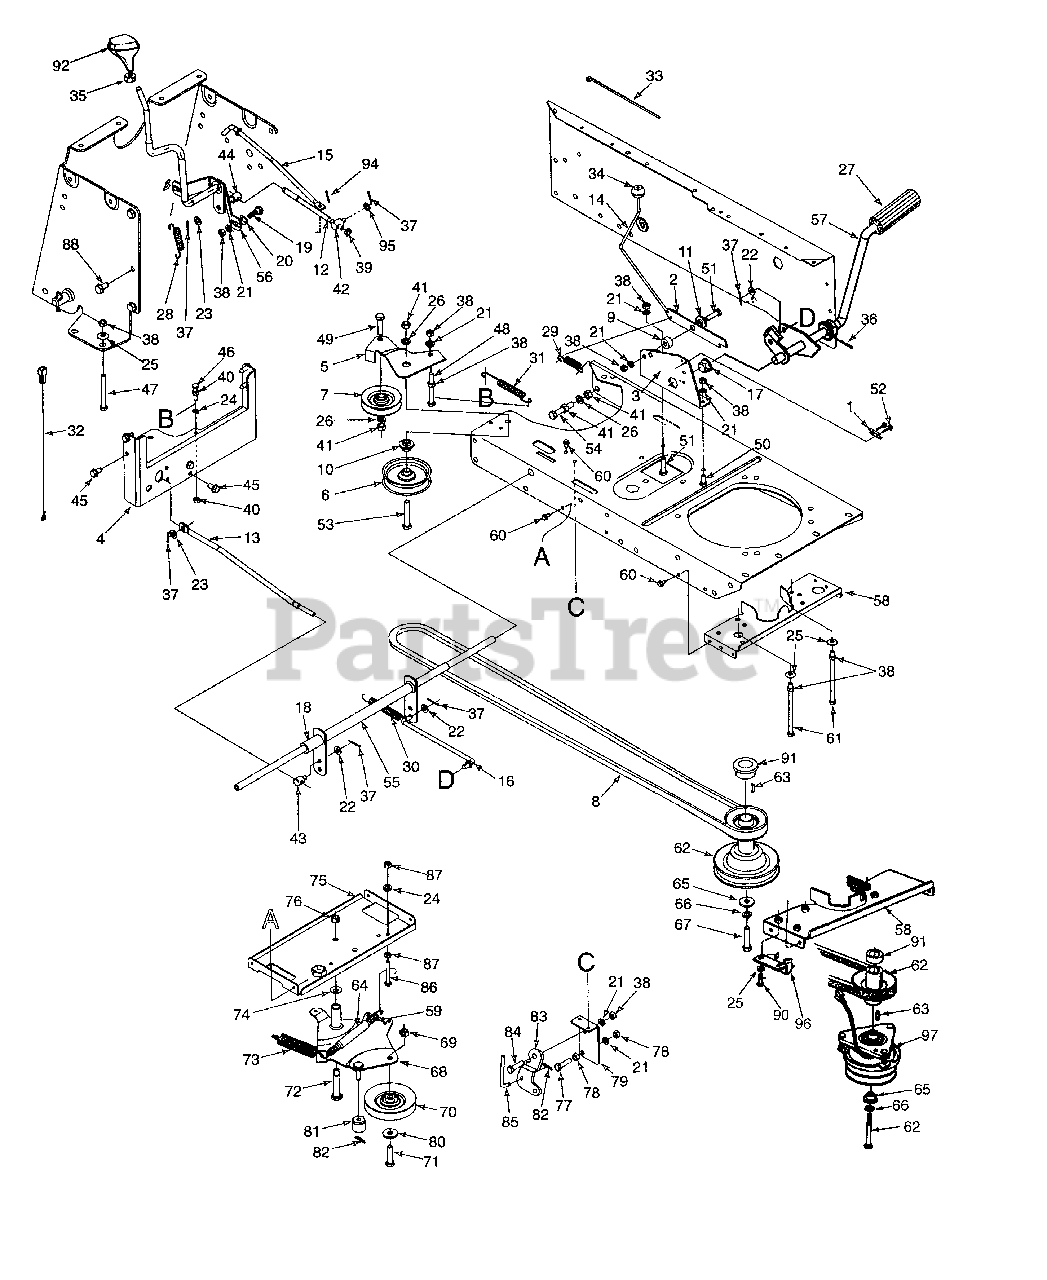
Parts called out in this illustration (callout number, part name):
1	Switch Plate
7	Idler Pulley
8	"V"-Belt
9	Spacer .34" I.D. x .44" Lg.
10	Shld. Spacer .38" I.D.
11	Shld. Spacer
12	Speed Selector Rod
13	Neutral Return Rod
14	Brake Lockout Rod
15	Hydro Disengagement Rod
16	Brake Link Rod
17	Hex Flange Bearing
18	Nyliner Flange Bearing
19	Shld. Bolt
20	Spr. Wash. 7/16" I.D.
21	L-Wash. 5/16" I.D.
22	Fl-Wash. 5/16" I.D.
23	Fl-Wash. .38" I.D.
24	L-Wash. 1/4" I.D.
25	Bell-Wash. .345" I.D.
26	L-Wash. 3/8" I.D.
27	Foot Pad
28	Ext. Spring 2.75" Lg.
29	Ext. Spring 2.51" Lg.
30	Ext. Spring 4.74" Lg.
31	Ext. Spring 4.97" Lg.
32	Transmission Wire
33	Cable Tie
34	Ball Knob
35	Hex Jam Nut 3/8-16 Thd. (Gr. 5)
36	Cotter Pin 1/8" Dia. x 1" Lg.
37	Cotter Pin 3/32" Dia. x 1" Lg.
38	Hex Nut 5/16-18 Thd. (Gr. 5)
39	Hex Jam Nut 5/16 Thd. L.H.
40	Hex Nut 1/4-20 Thd. (Gr. 5)
41	Hex Nut 3/8-16 Thd. (Gr. 5)
42	Ferrule 5/16-24 Thd. L.H.
43	Ferrule 5/16-18 Thd.
44	Ferrule 3/8-24 Thd.
45	Hex Wash. TT-Tap Scr. 5/16x .75" Lg.
46	Hex Bolt 1/4-20 x 1.25" Lg.
47	Hex Bolt 5/16-18 x 3" Lg.
48	Hex Bolt 5/16-18 x 2.75" Lg.
49	Hex Bolt 3/8-16 x 1.5" Lg.
50	Hex Bolt 5/16-18 x .75" Lg.
51	Hex Bolt 5/16-18 x 1.25" Lg.
52	Hex HD Tapp Scr. #10-16 x .75" Lg.
53	Hex Bolt 3/8-16 x 2.25" Lg.
54	Hex Bolt 3/8-16 x 2" Lg. (Gr. 5)
57	Hydro Foot Pedal Ass'y.
60	HexWash. TT-Tap Scr. 1/4-20 x .5" Lg.
61	Hex Bolt 5/16-18 x 5.25" Lg.
62	Engine Pulley
63	Sq. Key 1/4 x 1.5" Lg.
64	Convoluted Conduit
65	Fl-Wash. .45" I.D. x 1.25"
66	L-Wash. 7/16" I.D.
67	Hex Bolt 7/16-20 x 1.5" Lg.
68	Idler Brkt. Deck Ass'y.
69	Hex Cent. L-Nut 3/8-24 Thd.
70	Idler Pulley
71	Hex Bolt 3/8-24 x 1.5" Lg.
72	Shld. Bolt .498" Dia. x 2.05"
73	Ext. Spring 6.12" Lg.
74	Bell-Wash. .38" I.D. x .88" O.D.
76	Hex Cent. L-Nut 3/8-16 Thd.
77	Hex Bolt 5/16-24 x 1.25" Lg.
78	Hex Nut 5/16-24 Thd. (Gr. 5)
79	Parking Brake Mtg. Brkt.
80	Fl-Wash. .40" I.D. x .875" O.D.
81	Spacer
82	Hairpin Clip
83	Deck Control Pivot Brkt.
84	Shld. Bolt .437" Dia. x .162"
85	Deck Control Rod
86	Hex Bolt 1/4-20 x 2" Lg.
87	Hex Nut 1/4-20 Thd.
88	Hex AB-Tap Scr. 5/16 x .75"
90	Hex Bolt 5/16-18 x .75" Lg.
91	Clutch Spacer
92	Shift Knob
94	Hairpin Clip
95	Fl-Wash. .344" I.D. x .75" O.D.
